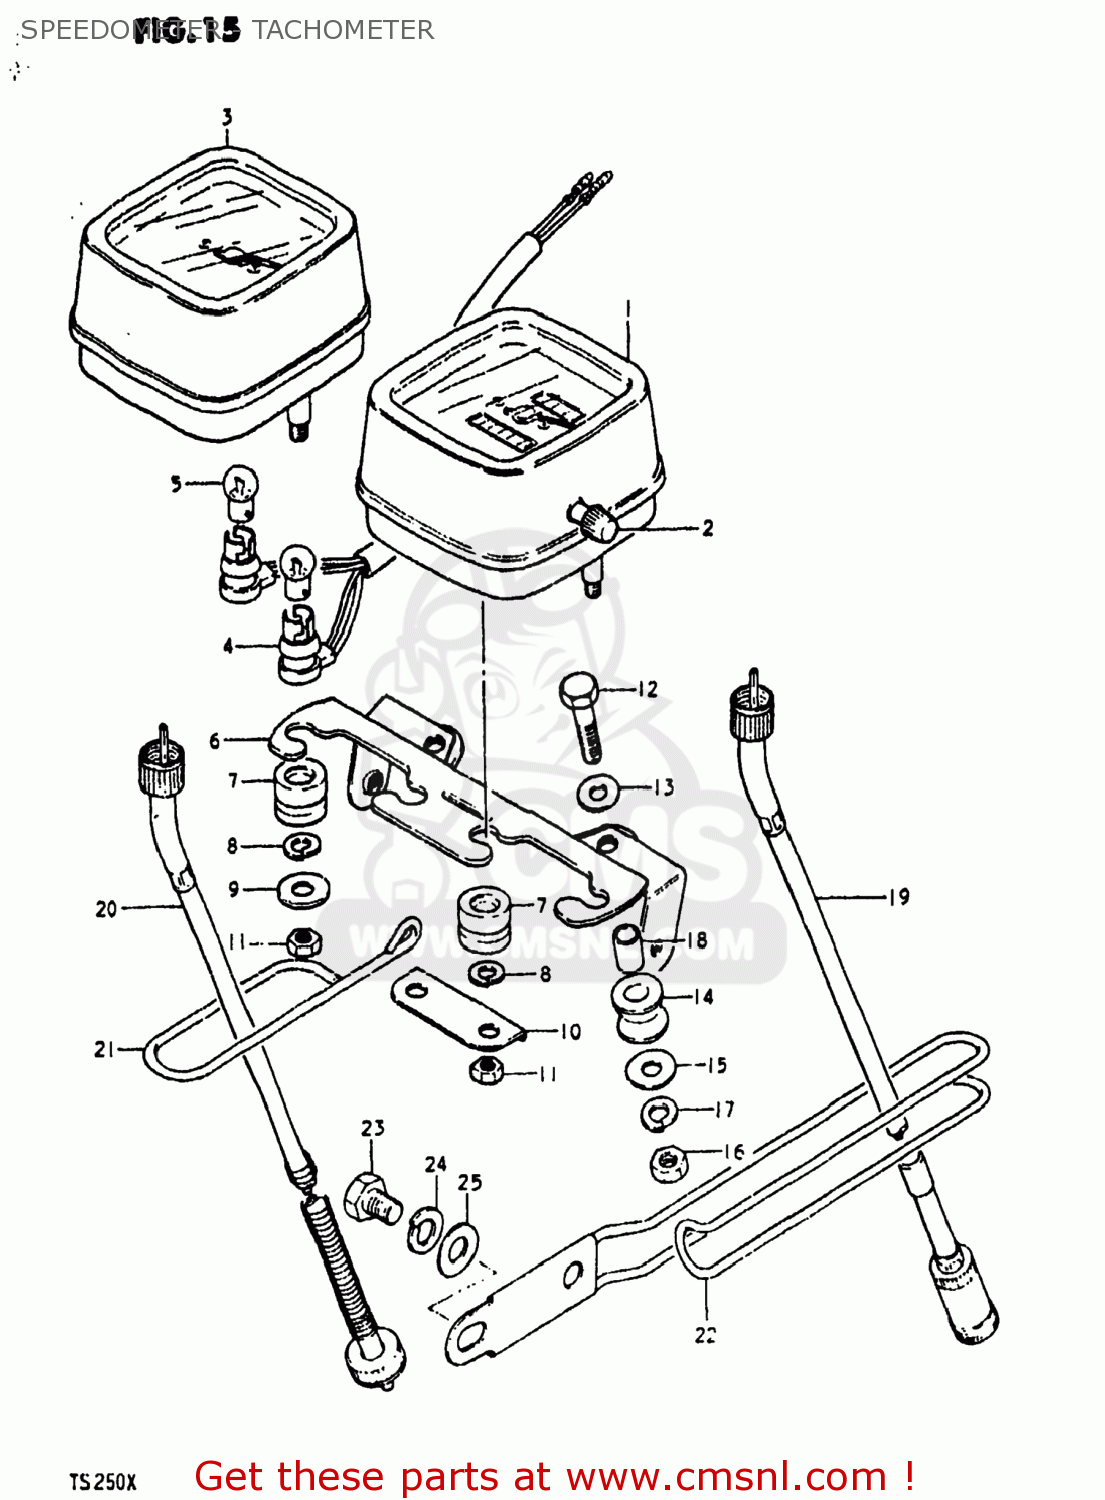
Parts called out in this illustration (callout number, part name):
1	SPEEDOMETER ASSEMBLY
2	KNOB,TRIP METER
3	TACHOMETER
4	SOCKET,METER
5	BULB(6V/3W)
6	BRACKET,COMBINATION METER
7	CUSHION
8	LOCK WASHER
9	WASHER,METER
10	PLATE,METER CONNECTING
11	NUT
12	BOLT
13	WASHER
14	CUSHION
15	WASHER
16	NUT
17	LOCK WASHER
18	SPACER (6.1X8X15.5)
19	CABLE ASSEMBLY,SPEEDOMETER
20	CABLE ASSEMBLY,TACHOMETER
21	GUIDE,TACHOMETER CABLE
22	GUIDE,CABLE
23	BOLT 8X12
24	LOCK WASHER
25	WASHER
